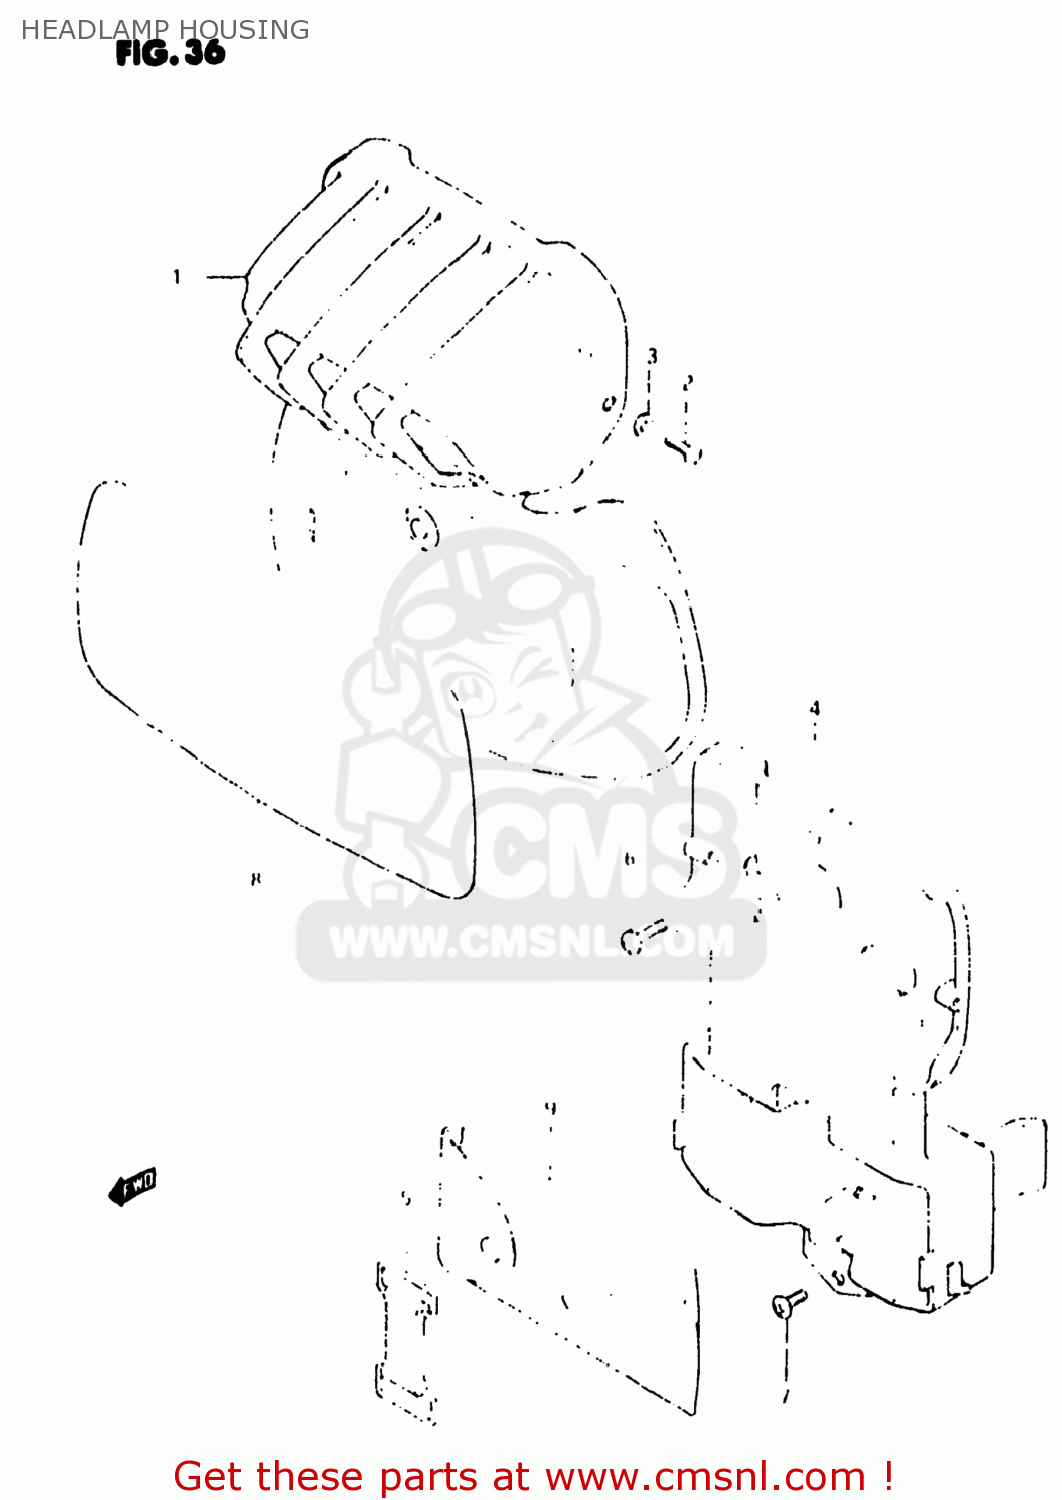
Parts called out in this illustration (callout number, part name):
1	HOUSING,HEADLAMP
2	TAPPING SCREW
3	WASHER
4	HOLDER,TOOL
5	BAND
6	SCREW
7	SCREW
8	EMBLEM,FRONT NUMBER PLATE
9	TOOL ASSY
